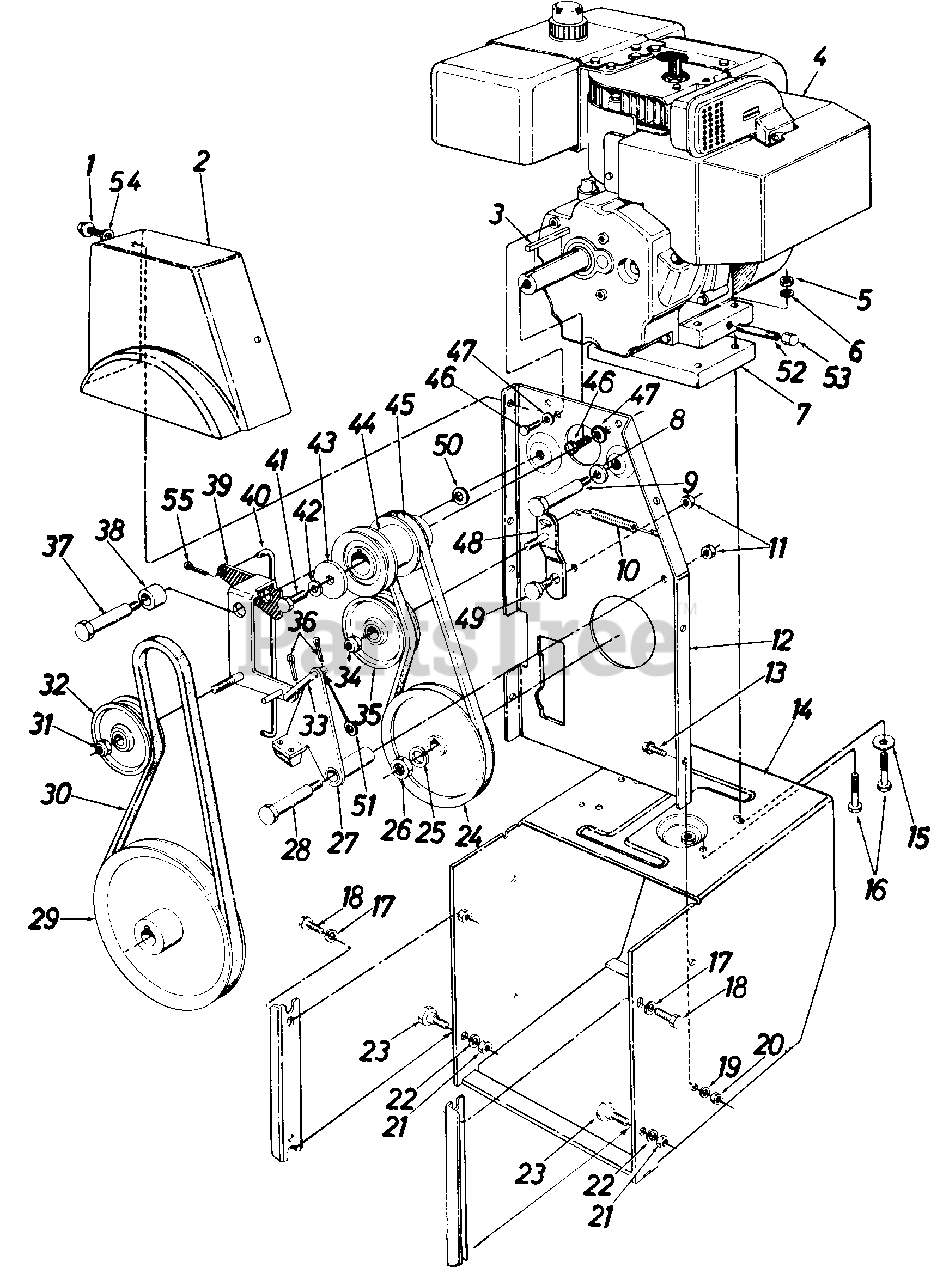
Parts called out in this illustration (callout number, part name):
1	Hex AB-Tap Scr. 5/16 x .75" Lg.
2	Belt Cover
3	Sq. Key 1/4" x 1.50" Lg.
4	Engine
5	Hex Nut 5/16-18 Thd.
6	L-Wash. 5/16" I.D.
7	Engine Spacer Ass'y.
8	Bell-Wash. .40 I.D. x .88 O.D.
9	Shld. Bolt .498" Dia. x 3.00" Lg.
10	Ext. Spring .38 O.D. x 3.18" Lg.
11	Hex Cent. L-Nut 3/8-16 Thd.
12	Engine Brkt. Ass'y.
13	Hex Sems Scr. 5/16-18 x . 75" Lg .
14	Frame Ass'y.
15	Fl-Wash. .345 I.D. .75 O.D. x .060
16	Hex Bolt 5/16-18 x 2.50" Lg.
17	L-Wash. 3/8" I.D. H.D.
18	Pilot Scr. 3/8-16 x .88" Lg.
19	L-Wash. 5/16" I.D.
20	Hex Nut 5/16-18 Thd.
21	Hex Nut 3/8-16 Thd.
22	L-Wash. 3/8" I.D. H.D.
23	Shld. Bolt .498" Dia. x .340" Lg.
24	V-Pulley .628 I.D. x 7.50 O.D.
25	L-Wash. for 5/8" I.D.
26	Hex Ins. Jam L-Nut 5/8-18 Thd.
27	Brake Brkt. Ass'y.
28	Shld. Bolt .498" Dia. x 2.00" Lg.
29	V-Pulley .875 I.D. x 10.12 O.D.
30	"V"-Belt
31	Hex Ins. Jam L-Nut 3/8-24 Thd.
32	Fl-ldler w/Flanges 3.0 O.D.
33	Brake Linkage Ass'y.
34	Hex Ins. Jam L-Nut 3/8-24 Thd.
35	3.0" O.D. Fl-ldler w/Flanges
36	Int. Cot. Pin 3/32" Dia.
37	Shld. Bolt .625" Dia. x 2 750" Lg.
38	Spacer .75 O.D. x 1.00" Lg.
41	Hex Bolt 3/8-24 x 1.25" Lg.
42	L-Wash. 3/8" I.D. H.D.
44	Engine Pulley-Double Groove
45	"V"-Belt
46	Hex Bolt 5/16-24 x .62" Lg.
47	Bell-Wash. .345 I.D. x .88 0 O.D. x .060
48	Drive Idler Brkt. Ass'y.
49	Shld. Bolt-.625" Dia. x .170" Lg.
50	Bell-Wash. .40 I.D. x 1.12 O.D.
51	Fl-Wash. .385" I.D. x .620" O.D.
52	Pipe Nipple-1/4" Pipe Thd. x 3.5" Lg.
53	Hex Hd. Cap 1/4-18 Pipe T
54	Fl-Wash. .340 I.D. x .62 O.D. x .62
55	Int. Cot. Pin 5/16" Dia.
